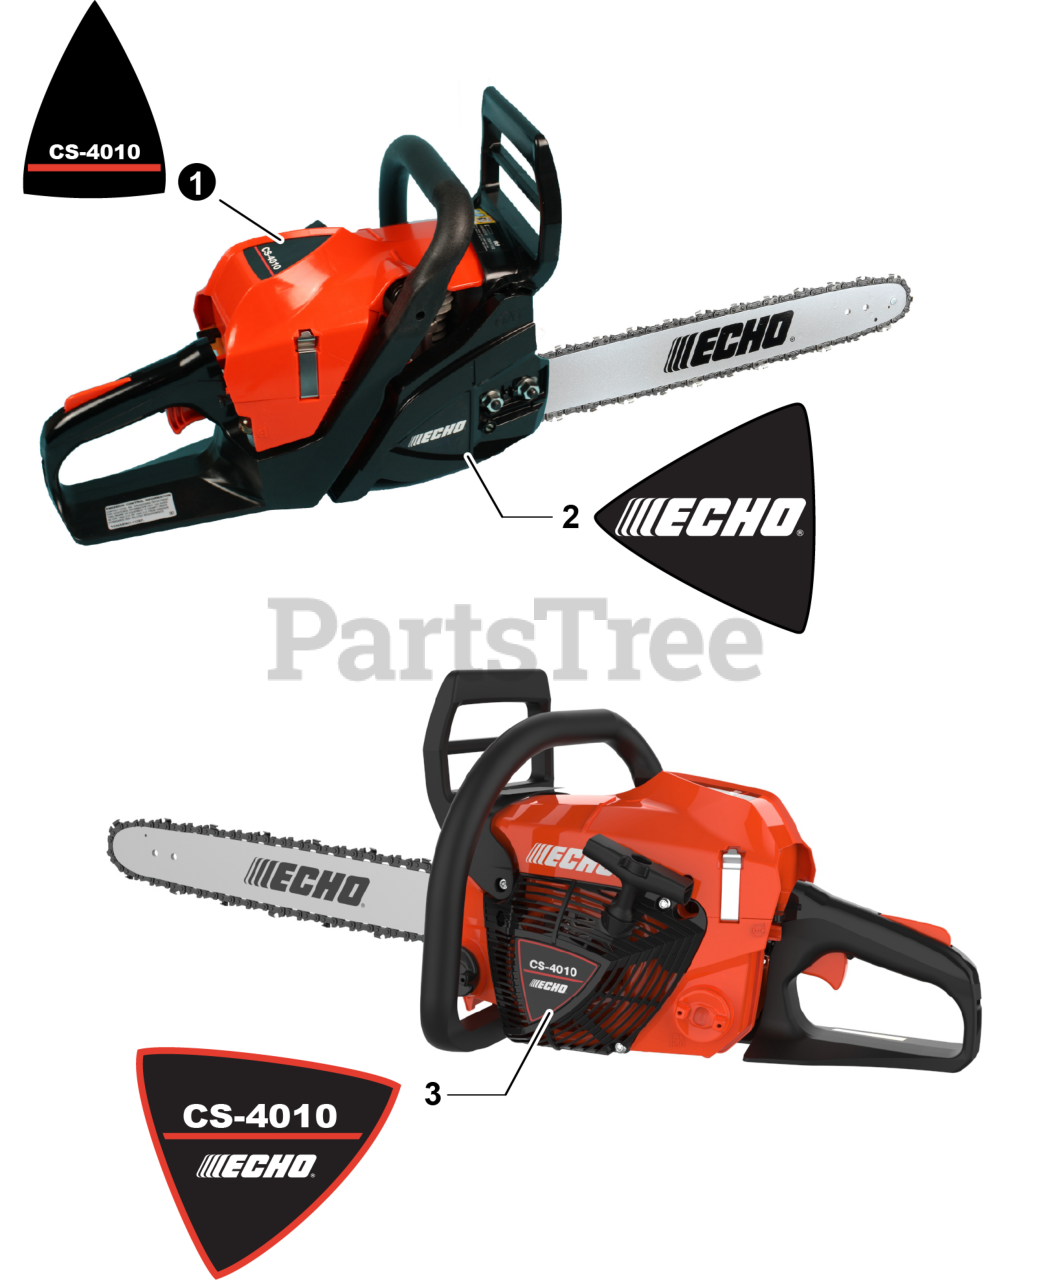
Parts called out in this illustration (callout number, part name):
1	LABEL - CS-4010
2	LABEL - ECHO
3	LABEL - STARTER - CS-4010
